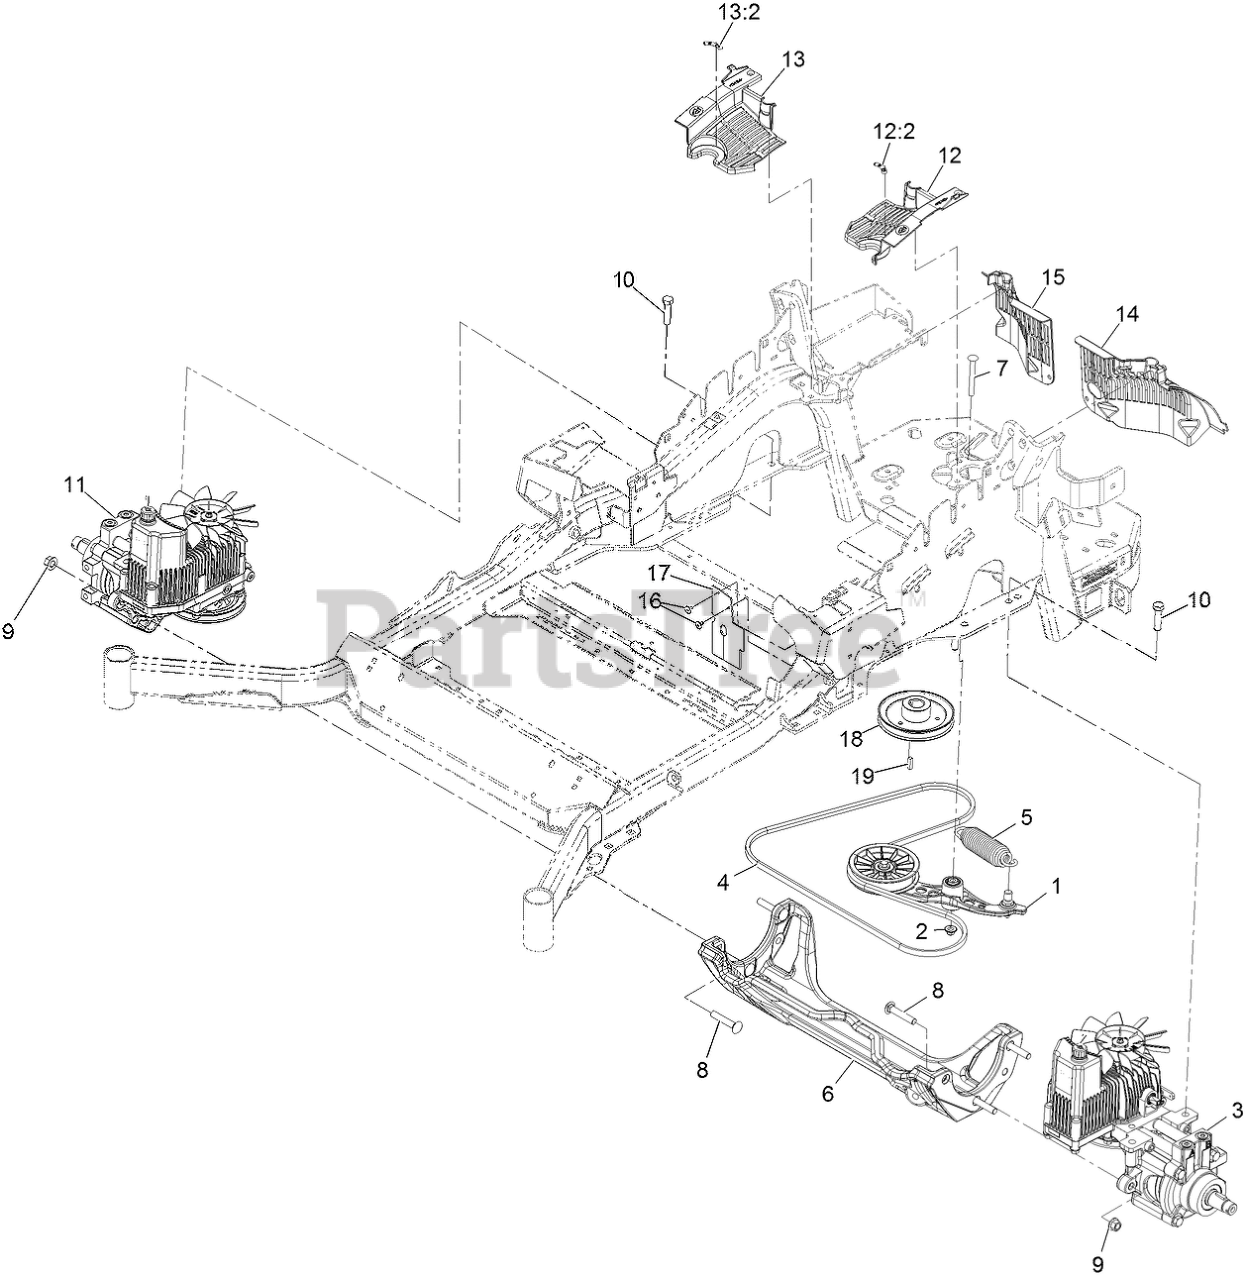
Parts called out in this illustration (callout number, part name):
1	PUMP IDLER ASM
2	Nut-Nyloc 3/8-16 Flg
3	HYDRO-LH
5	SPRING-EXTENSION
6	CRADLE-HYDRO
7	BOLT-SHOULDER, CARRIAGE 3/8-16 X 3 1/2
8	SCREW-CARR
9	Nut-Lock 1/2-13
10	SCREW-HH
11	HYDRO-RH
12	LH HYDRO GUARD ASM
12:2	DECAL-OIL, HYDRO
13	RH HYDRO GUARD ASM
13:2	DECAL-OIL, HYDRO
14	GUARD-HYDRO, REAR (LH)
15	GUARD-HYDRO, REAR (RH)
16	RIVET-POP
17	DEFLECTOR-AIR FLOW
18	SHEAVE
